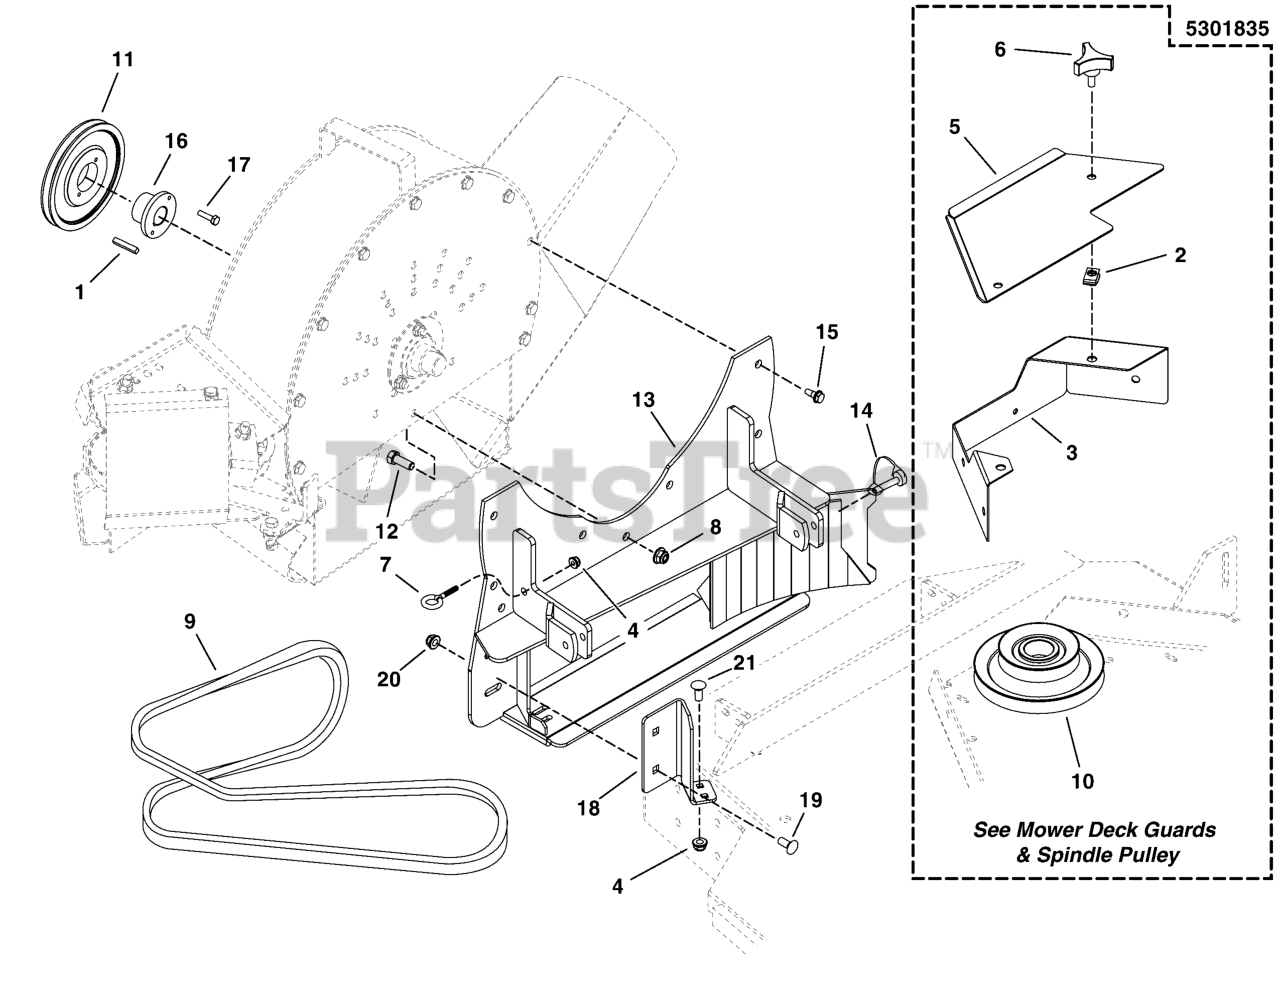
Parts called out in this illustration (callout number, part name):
1	KEY 1/4 SQ X 1 1/2 LONG
2	BODY CLIP, 5/16-18-7GA MATERIAL
3	SEE MOWER DECK GUARDS & SPINDLE PULLEY
4	NUT, 1/4-20 Hex Nylock Flange
5	SEE MOWER DECK GUARDS & SPINDLE PULLEY
6	KNOB, PLASTIC, 5/16-18 X 3/4"
7	EYE BOLT, 1/4-20 X 2.5, 1THRD, .5EYE,CZ
8	NUT, 3/8 - 16 HEX NYLOCK FLANGE
9	BELT, 96" EL, A-SECT, ARAMID, WRAPPED
10	SEE MOWER DECK GUARDS & SPINDLE PULLEY
11	PULLEY, BLOWER AXLE, 61
11	PULLEY , 4.75 OD, SINGLE GROOVE BH-48
12	BOLT, 3/8-16 X 1" GD5 CZ
13	WELD, ADAPTER, 61ICD, FVAC - BLK
14	SNAPPERPIN, 5/16 X 2
15	BOLT, 5/16-18 X 5/8" Self Lock
16	BUSHING, Tapered Hub
17	BOLT, 1/4-20 X 1" GD5 CZ
18	BRACKET, DEFLECTOR PLATE, 61" iCD - BLK
19	BOLT, 5/16-18 X 3/4, CARRIAGE, GD5, CZ
20	NUT, 5/16-18 HEX NYLOCK FLANGE NUT
21	BOLT-RD HD SH SQ NK 1/4-20X0. 625 G5 BLK
